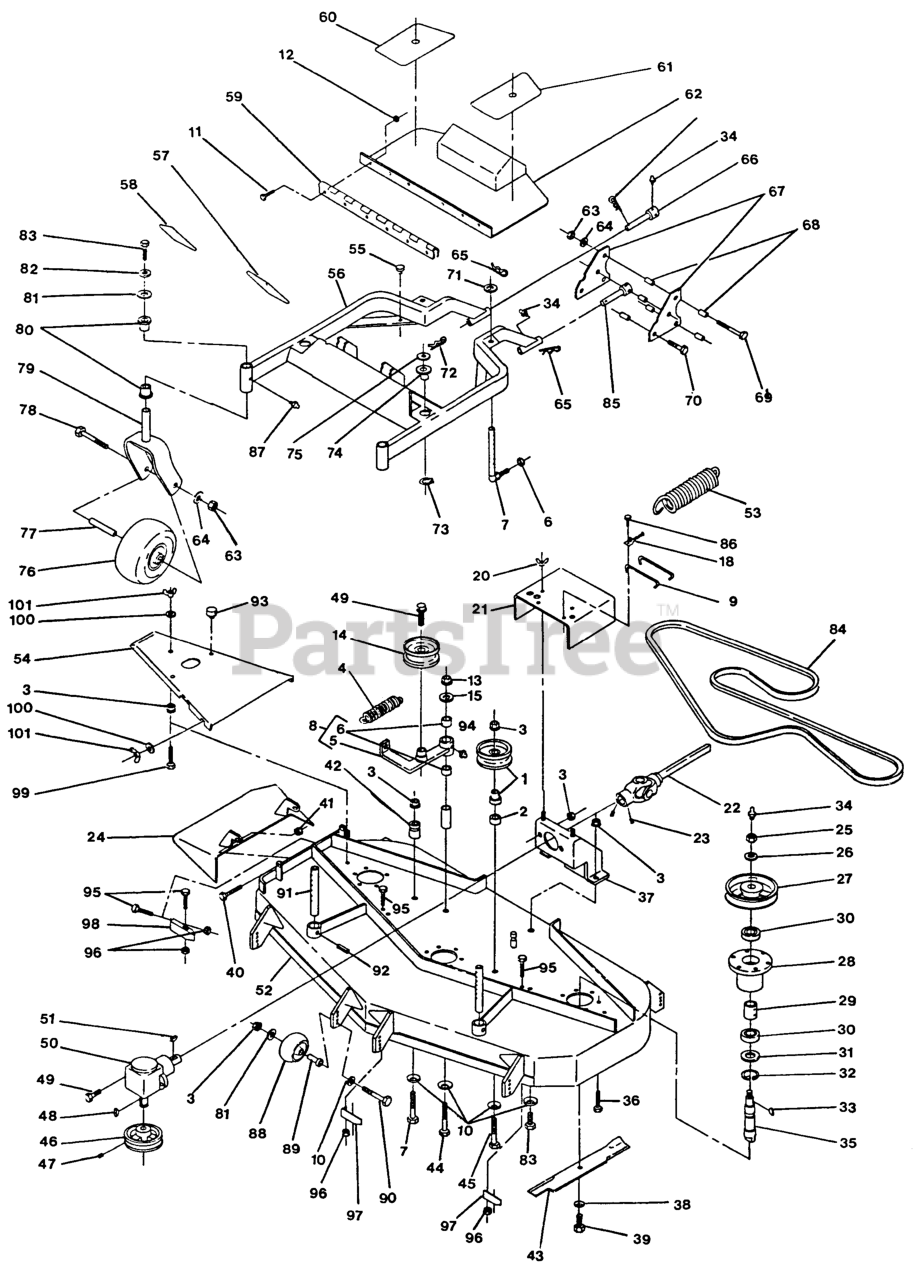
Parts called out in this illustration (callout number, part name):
1	KIT,48 RH IDLER/BUS
9	BUSHING
14	IDLER,PULLEY
18	CLIP-DECK, HOLD UP ROD
20	WINGNUT-NYLOCK
22	PTO SHAFT,SHAFT HALF PNT
26	WASHER-SPRING
27	SHEAVE,BLADE DRIVE
29	SPACER,BEARING
31	SEAL,MECHANICAL DUST
32	RING,SNAP WLDS N5000-244
35	SPINDLE-OUTER BLADE
36	SCRW,TPTTE HH
37	WLD,GEARBOX SUPPORT
38	WASHER-SPRING
42	ANCHOR-SPRING PLTD
47	SCREW-SET
57	PAD,ANTI SKID UPPER LH
58	PAD,ANTI SKID UPPER RH
59	HINGE,FLOORPAN
60	PAD,ANTI SKID LOWER RH
65	PIN,HAIR COTTER
71	SPACER,REAR DK SUPP PLTD
74	BUSHING-DECK
75	SPACER-CASTER
80	BEARING-FLANGED
86	Pop Rivet, Steel 3/16 X .250
88	ROLLER-SCALP, ANTI
89	BUSHING-ROLLER
91	ROD,DECK SUPPORT
98	WLD,BAFFLE DISCHARGE
101	NUT-WING
